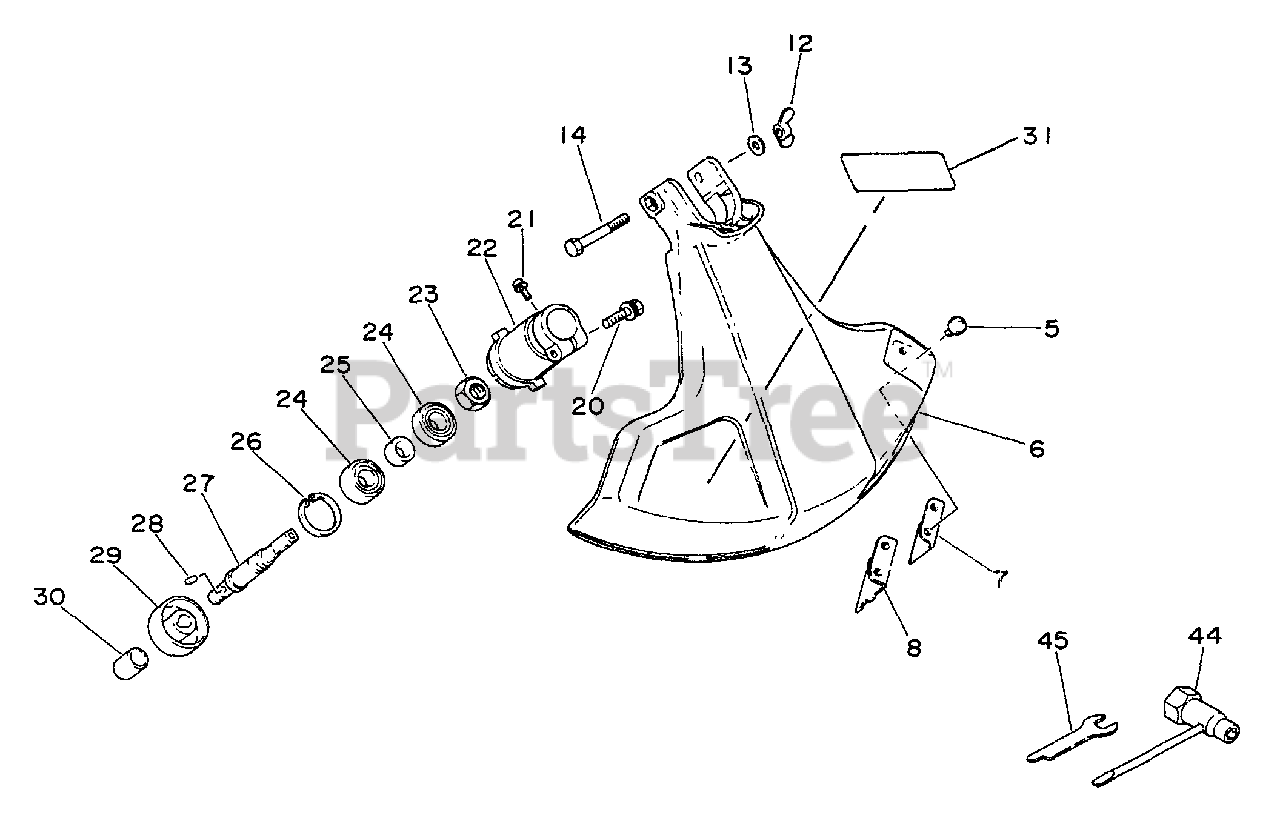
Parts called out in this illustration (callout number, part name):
5	SCREW - 5X16
6	SHIELD, DEBRIS - PLASTIC
7	KNIFE, TRIMMER LINE
8	GUARD
12	WINGNUT - 6
13	WASHER - 6
14	BOLT - 6X50
20	BOLT - 5X25
21	SCREW - 4X10
22	CASE, GEAR
23	NUT - 12 -- LEFT HAND
24	BEARING, BALL - 6001 DDU
26	RING, RETAINING - 28
27	GEAR - SHAFT
28	PIN - 3X6
29	ADAPTOR, BLADE - UPPER
30	CAP, DRIVESHAFT
31	LABEL - ECHO
44	T-WRENCH - 8X19mm
45	SPANNER - 10mm
